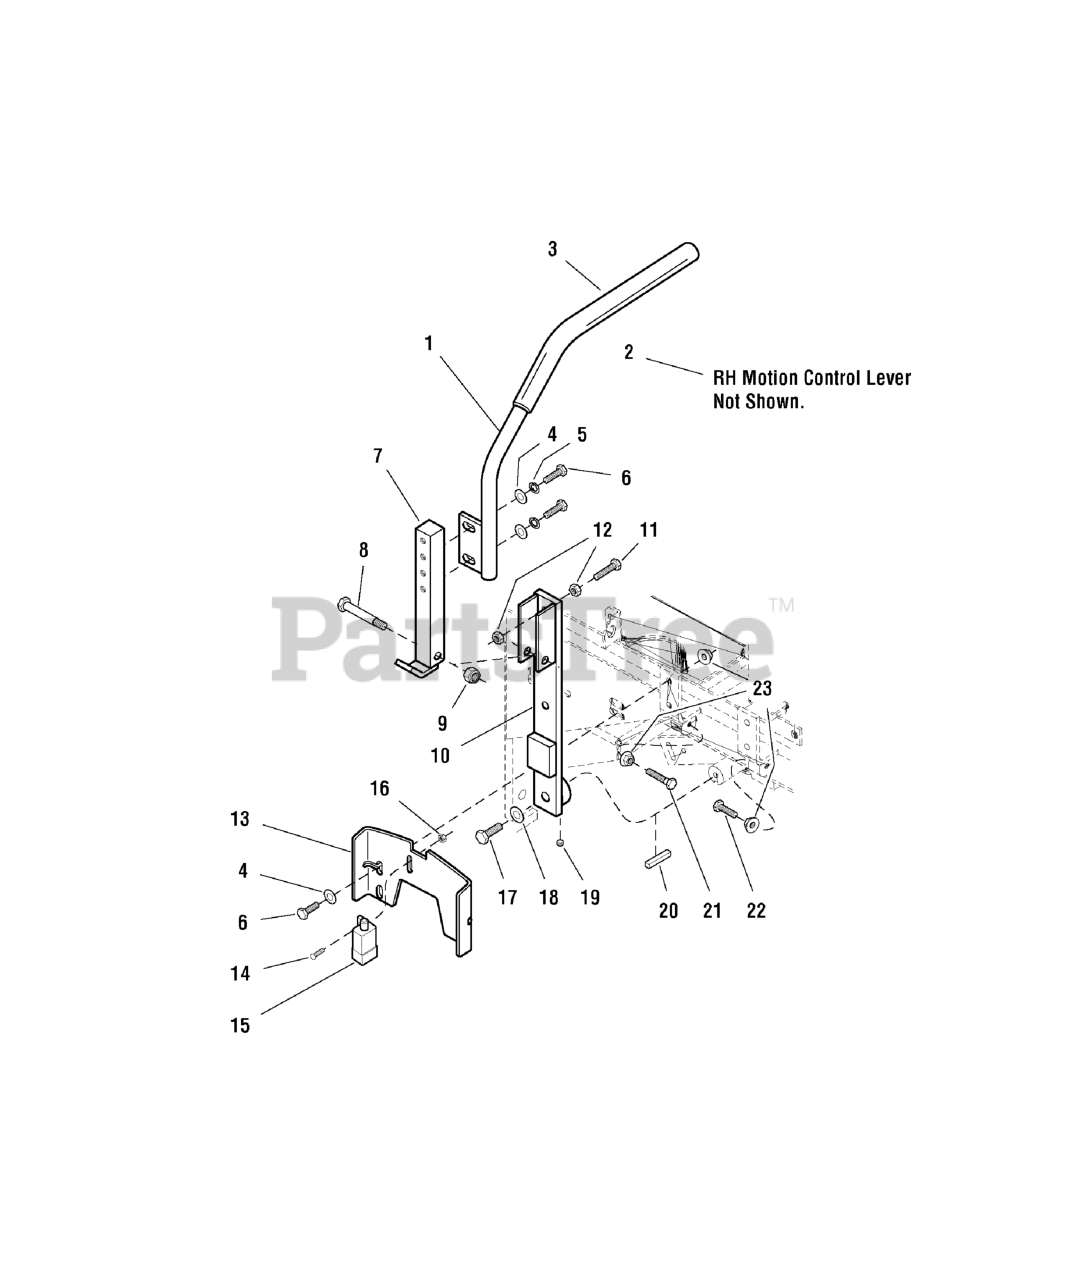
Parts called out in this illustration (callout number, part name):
1	MOTION CONTROL LEVER-RH
3	GRIP, Foam
4	WASHER, 5/16" SAE
5	WASHER, 5/16 LOCK CZ
6	BOLT, 5/16-18 X 3/4 GD5
7	WELD, CONTROL HANDLE BASE
8	BOLT, 3/8-16 X 2, GD5, CZ
9	NUT, 3/8-16 HEX NYLON LOCK
10	WELD, CONTROL LEVER, 2" BLOCK
11	BOLT, 5/16-18 X 1 GD5 YZ
12	NUT, 5/16-18 HEX
13	NEUTRAL LOCK PLATE
14	SCREW, #10-24 X 1 RS, CZ
15	SWITCH (see electrical group)
16	NUT, #10-24 Hex
17	BOLT, 3/8-16 x 1-1/4 w/ patch
18	WASHER, 3/8 SAE
19	SET SCREW, 5/16-18 x 1/4 w/ patch
20	KEY, 1/4 SQ. X 1
21	BOLT, 5/16-18 x 1-3/4
22	BOLT, 5/16-18 x 1-1/4
23	NUT, 5/16-18 HEX SERRATED FLANGE (SMALL)
